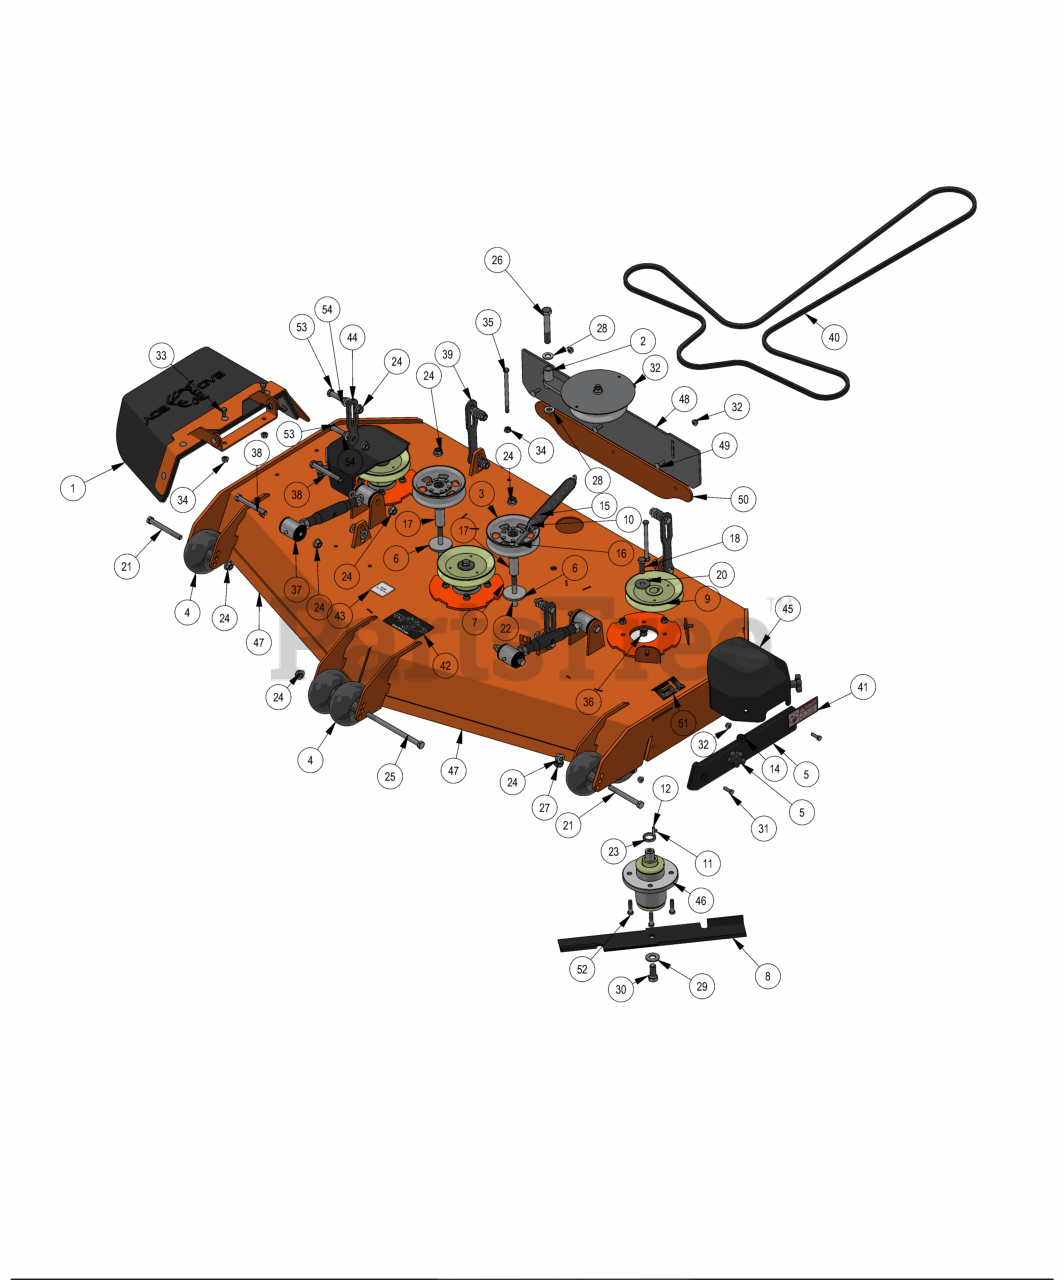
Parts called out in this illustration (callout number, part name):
1	2019 Outlaw Gen2 Chute Assembly
2	2020 61 Revolt Deck Idler Assembly
3	5-3/4 Idler Pulley
4	2019 Deck Wheel
5	REVISED TRIM BUMPER_20180226
6	MZ Deck Idler Spacer
7	Deck Spindle Support Plate
8	61 inch Fusion Blade
9	6 1/4" Drive Pulley
10	2019 Outlaw Gen2 Deck Spring
11	5/16-24 X 1/4 SOCKET SET SCREW (CUP PT) PLAIN
12	1/4 X 1 SQ MACHINERY KEY 1018 STL PLN
13	5/16" Knob
14	.360 ID X .983 OD X .120 THICK FLAT WASHER NYLON BLACK
15	1/2-13 HEX NUT ZINC
16	All Thread
17	2019 Revolt Stationary Idle Spacer
18	1/2-20 X 1-1/2 HEX CAP SCREW (GR.5) ZINC
19	1/2 SPLIT LOCKWASHER (GR.8) ZINC/YELLOW
20	1/2 BELLEVILLE WASHER (1-5/8 OD X .140 THK) ZINC
21	1/2-13 X 4-1/2 HEX CAP SCREW (GR.5) ZINC
22	1/2-13 X 4-1/4 HEX CAP SCREW (GR.5) ZINC
23	1.02 ID X 1.38 OD X .250 THK SPACER ZINC
24	1/2-13 NYLON INSERT FLANGE LOCKNUT ZINC
25	1/2-13 X 8 HEX CAP SCREW GR 5 ZINC
26	5/8-11 X 4 HEX CAP SCREW (GR.8) ZINC YELLOW
27	5/8-11 NYLON INSERT JAM LOCKNUT ZINC
28	.635 ID X 1.120 OD X .140 THICK FLAT WASHER NYLON
29	5/8 USS FLAT WASHER (1-3/4" OD) GR.8 ZINC YELLOW
30	5/8-18 X 1-1/2 HEX CAP SCREW (GR.8) ZINC YELLOW
31	5/16-18 X 1 HEX CAP SCREW (GR.5) ZINC
32	5/16-18 NYLON INSERT FLANGE LOCKNUT ZINC
33	3/8-16 X 3/4 HEX CAP SCREW (GR.5) ZINC
34	3/8-16 HEX SERRATED FLANGE NUT HARD/ZINC
35	3/8-16 X 5-1/2 HEX CAP SCREW (GR.5) ZINC
36	3/8-16 NYLON INSERT FLANGE LOCKNUT (GR.F) ZINC
37	Turnbuckle
38	1/2-13 X 4 HEX CAP SCREW (GR.8) ZINC YELLOW
39	2023 Stand-On Rear Deck HangerV2
41	Danger Decal-Spindle/Discharge
42	2019 Revolt Deck Belt Route Decal
43	Deck Impact Patent Decal 9591803
44	2023 revolt 61 front hanger V2
45	2023 Revolt pulley cover
46	OUTLAW SPINDLE ASSEMBLY
47	2023 61'' DECK
48	2023 MZ Stripping Kit Rubber
49	5/16-18 X 1 CARRIAGE BOLT (GR.8) ZINC
50	Striping Kit Plate
51	61" Deck Decal
52	3/8-16 X 1-1/2 HEX CAP SCREW (GR.5) ZINC
53	1/2-13 X 2-1/4 HEX CAP SCREW (GR.5) ZINC
54	1/2-13 HEX SERRATED FLANGE NUT HARD/ZINC
55	.505 ID X 1.000 OD X .125 THICK FLAT WASHER NYLON
